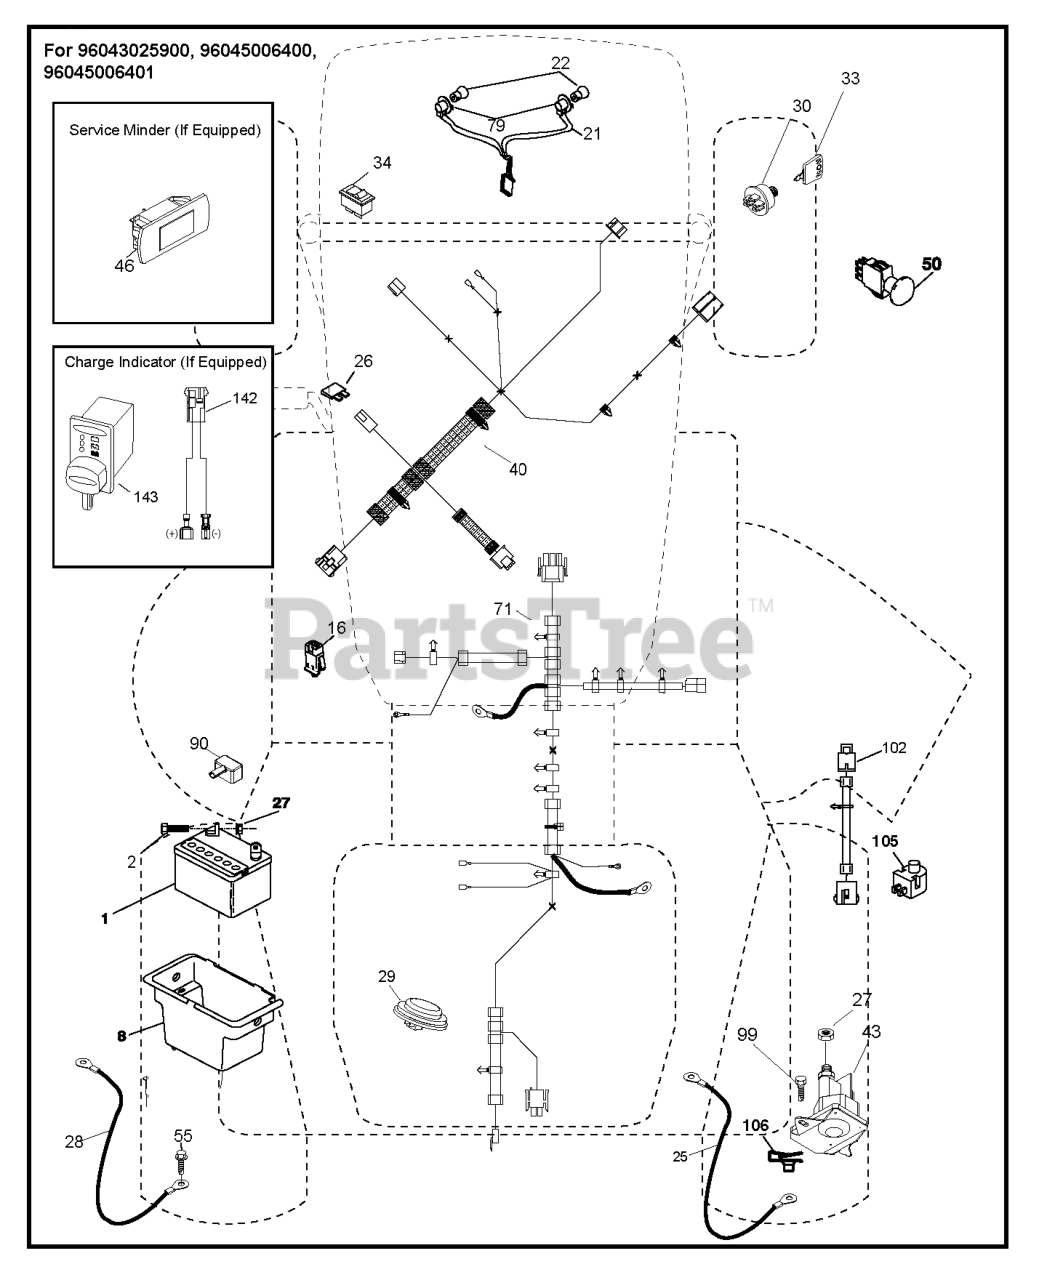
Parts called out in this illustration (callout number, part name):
1	Battery 12 Volt 25 Amp
2	BOLT.HEX.1/4.X.3/4.DICHROMATE
8	BOX.BATTERY.MNT.REAR.L
16	SWITCH INTERLOOK PUSH-IN
21	HARNESS.LIGHT W/4152J BULBS
25	CABLE.BATT.RED.8GA.17
26	FUSE 20AMP
28	CABLE.GROUND.REAR.BATTERY.8G
29	SWITCH.SEAT.DELTA.OPC.
30	SWITCH.IGN.DELTA.W.LGH.ROS
33	KEY.CHAIN.BLISTER.PACK.GEN.INT
33	KEY.CHAIN.BLISTER.PACK.GEN.USA
40	HARNESS.TEX.DASH.ELEC.REAR BAT
46	GUAGE.SRVCMNDR.HRMTR.
50	RP SWITCH.PTO.TERMINAL.STD.RED
55	SCREW 5/16"
71	HARNESS.CHASSIS.RRBATT.RDYSTRT
79	BULB HOLDER ASM.
90	COVER.TERMINAL.BATTERY
99	SCREW HEXWSHR 1/4-20X3/4
102	HARNESS PIGTAIL PCH TEX ROS
105	REVERSE SWITCH
106	1/4-20 U NUT
